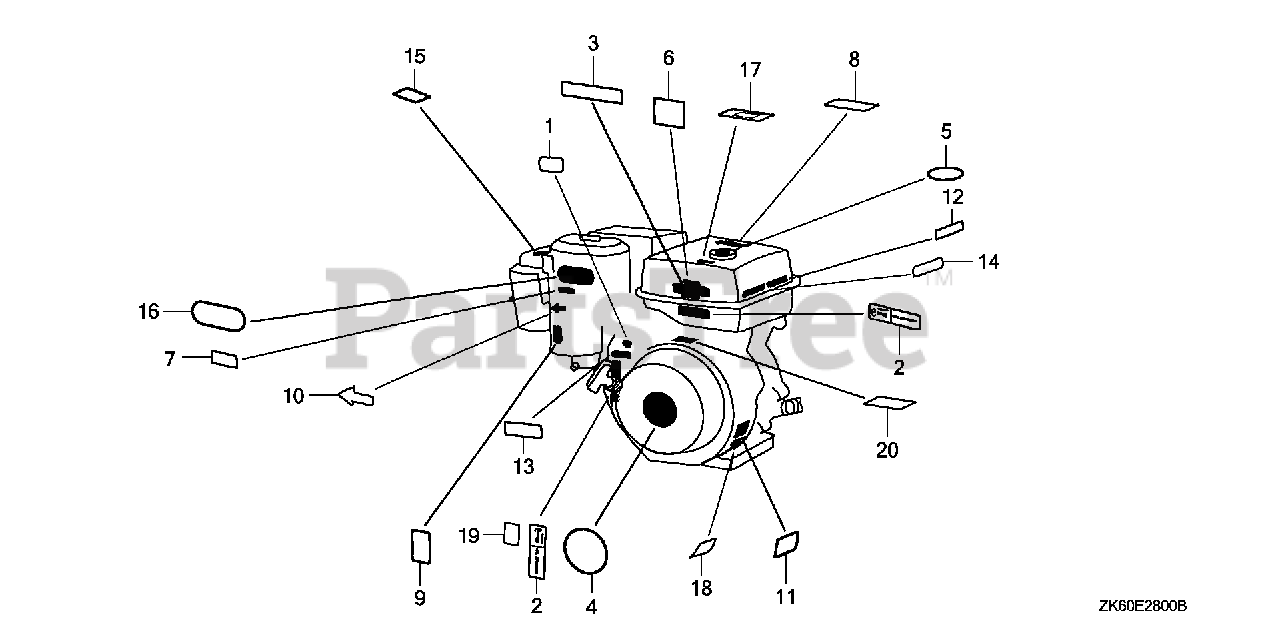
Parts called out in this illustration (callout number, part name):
4	EMBLEM (13. (HONDA)
4	EMBLEM (GX390) (HONDA)
12	MARK, OIL ALERT (FRENCH)
